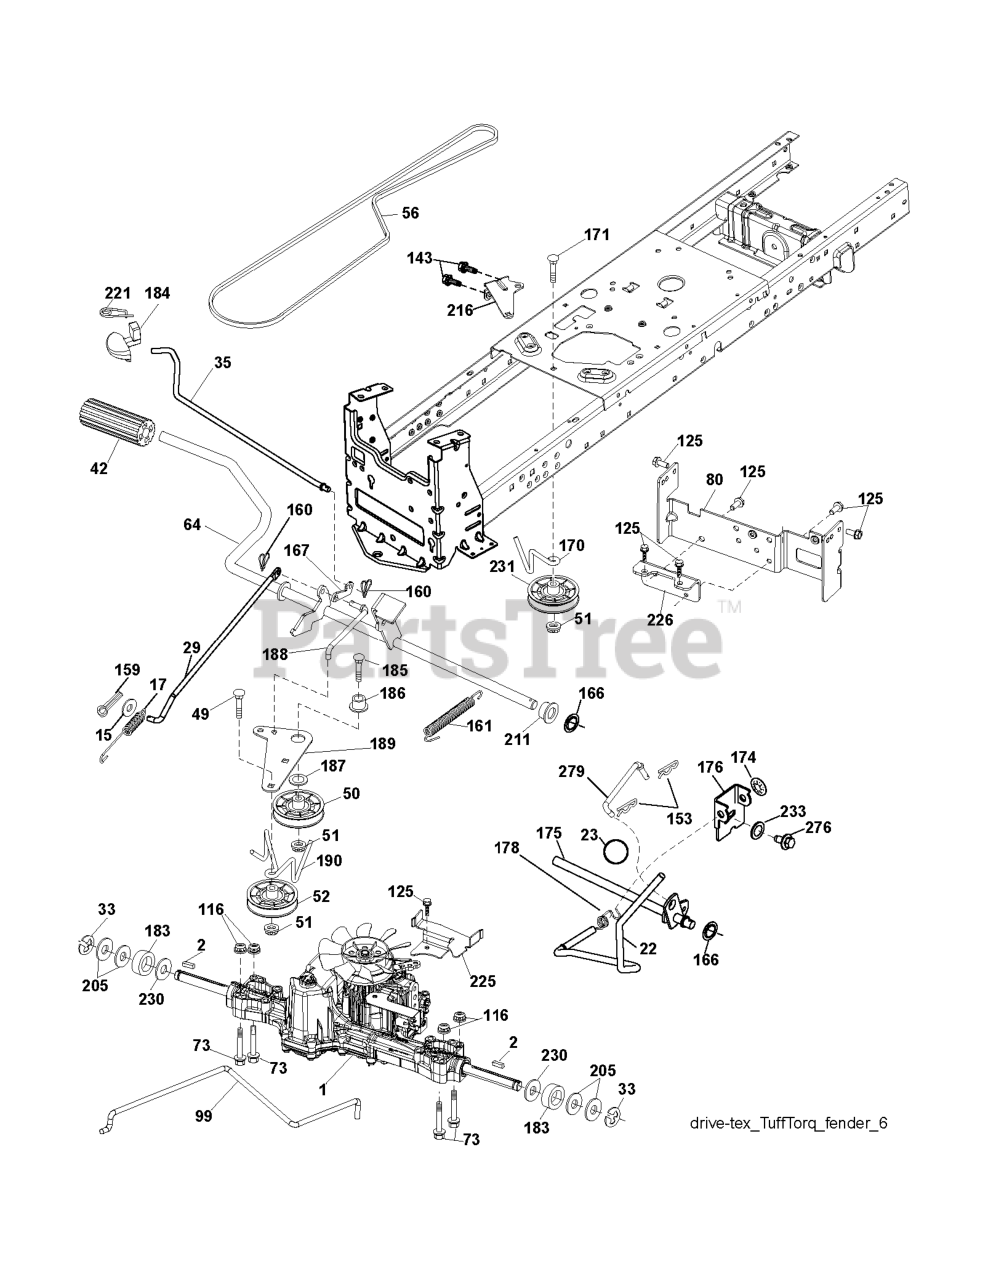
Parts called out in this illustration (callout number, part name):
2	SQUARE KEY
15	WASHER
17	SPRING.BRAKE.K46.GREEN
22	ROD.SHIFT.FENDER.TLT.2006
23	KNOB.DUCKHEAD.1/2
29	ROD.BRAKE.K46
35	ROD.CNTRL.PARK.PREDATOR.LT.TEX
42	PEDAL COVER T
50	IDLER.FLAT.910.OFFSET
51	NUT LOCK FLG 3/8-16 UNC
52	IDLER.V-GROOVE.910.OFFSET
56	V-BELT.MOWER.92.40.42/K46
64	SHAFT.ASM.PEDAL.BRAKE.
73	BOLT HEX 5/16-18 GR 5
80	STRAP TORQUE
99	ROD ASM BYPASS
116	NUT LOCK HEX FLANGE 5/16-18
125	SCREW
143	Screw 5/16-18 x 1/2 Hex, Self Tapping 5/16-18 x 1/2
153	RETAINER M
159	COTTER PIN
160	RETAINER CLIP
161	SPRING, RETURN LT
166	NUT.PUSH.625.2006
167	LATCH.BRAKE.SPRING
170	KEEPER.V-IDLER.CENTER.
174	NUT.PUSH.500.2006
175	SHAFT.ASM.SHFT.T2.TLT
176	ARM.CLEVIS.ROD.SHIFT
178	SPRING.SHIFT.GT2006
183	SPACER AXLE
184	HANDLE PARKING BRAKE
186	SPACER.RETAINER
187	WASHER 12/32X2X10GA
188	RP.LINK.CLUTCH.GROUND.DRIVE
189	BELLCRANK.GROUND.DRIVE.TEX.
190	KEEPER.BELLCRANK.DRIVE
211	BUSHING.SHAFT.BRAKE.HAND
216	BRACKET.PULLEY.IDLER.W/TEX
221	RETAINER.SPRING.CLIP.H
225	KEEPER.BELT.TRANSAXLE.K46
226	STRAP TORQUE.ASM.K46/18"TEX
230	WASHER.HARDENED
231	IDLER.V-GROOVE.1.688.OFFSET
233	WASHER SERRATED
276	BOLT FIN HEX 7/16-14 X 1
279	LINK.SHIFT.
